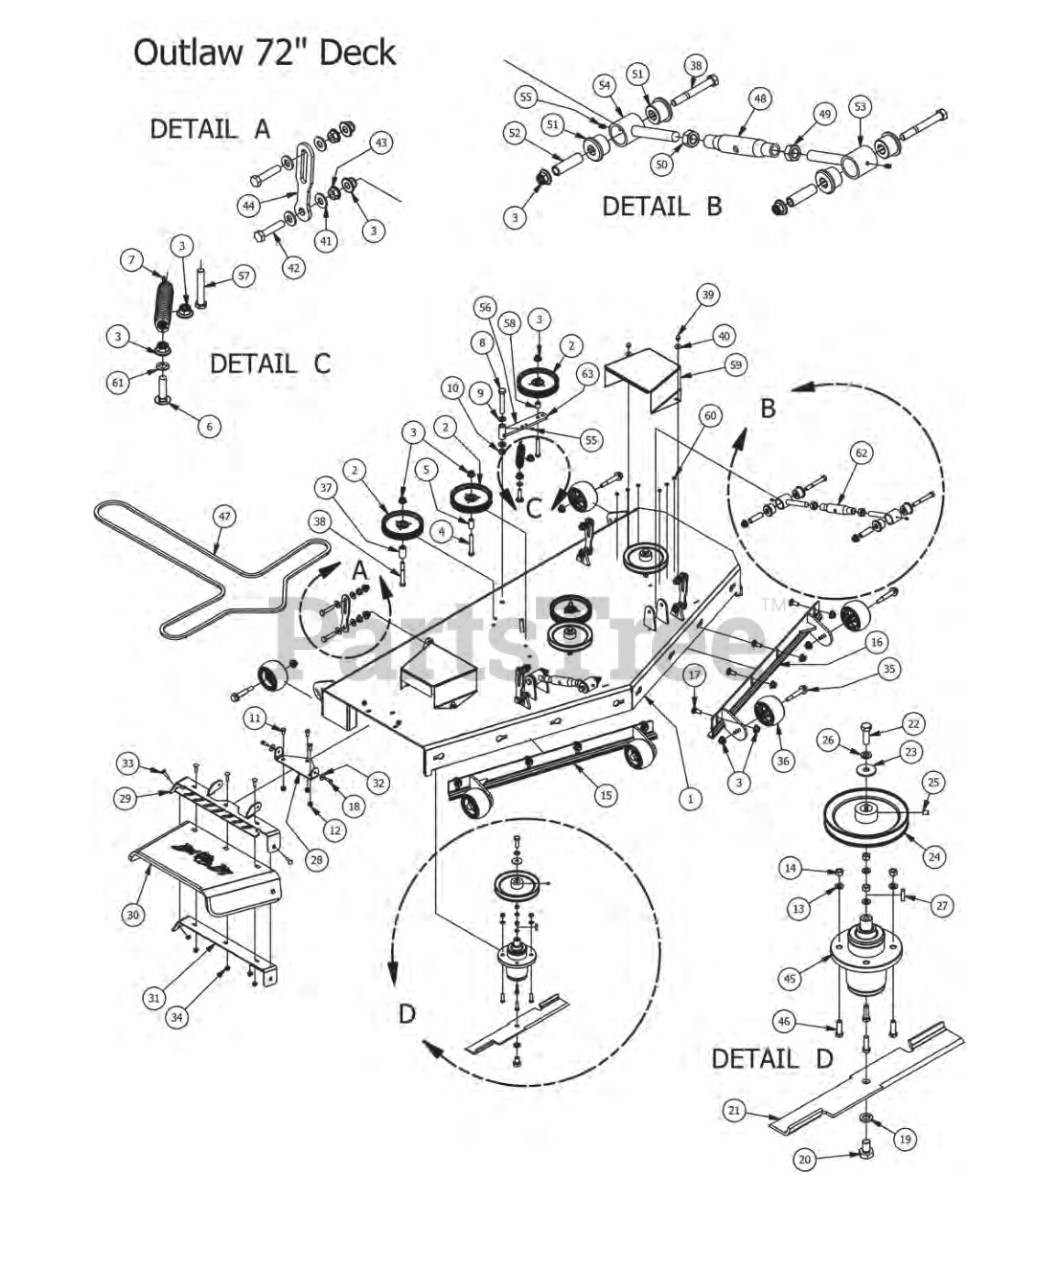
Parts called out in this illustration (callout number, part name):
1	2015 72" Deck
2	5-3/4 Idler Pulley
3	1/2-13 Nylon Flange Nut-Orange
4	1/2 x 3 1/2 Flange Bolt Grade 8
5	502 ID X.75 OD X 1.500 Leng
6	1/2 x 2" Carriage Bolt
7	2015 Deck Idler Spring Outlaws
8	5/8" x 4" Hex Bolt
9	635 ID Plastic Washer
10	5/B-11 Nylon Insert Jam Half Nut
11	3/8" x 3/4" Hex Bolt
12	3/8" Flange Nut
13	3/B Lockwasher Zinc
14	3/B-16 Hex Nuts Zinc
15	72" Deck Adustable Front (Right)
16	72" Deck Adjustable Front (Left)
17	1/2" x 1 1/4 Carriage Bolt
18	5/16" x 1" Bolt
19	5/8" Lock Washer
20	5/8" x 1 1/2" Gr8 Hex Bolt (Fine)
21	72" High Lift Fusion Blade
22	1/2"-20 x 1 1/2-Grade 5 Fine Thread Bolt
23	1/2 Belleville Washer
24	7 Deck Pulley
25	5/16 Set Screw
26	1/2" Lock Washer
27	1/4" x 1" Key
28	Discharge Chute Hanger (deck mounted)
29	60" Discharge Chute Upper Hanger
30	Rubber Discharge Chute
31	60" Discharge Lower Bracket
32	360 ID Plastic Washer
33	5/16" x 1 1/4" Carriage Bolt
34	5/16" Flange Nut Zinc W/Serrations
35	Deck Wheel Bolt
36	Anti-Scalp Rollers.
37	13/4" Pulley Spacer
38	1/2" x 4" Bolt (Grade 8)
39	Acom nut-pulley Cover
40	360 ID Plastic Washer-Black
41	505 Nylon Spacer
42	1/2-13X 2-1/4 GR Hex Bolts
43	1/2" Flange Nut
44	Deck Hanging Tab
45	OUTLAW SPINDLE ASSEMBLY
46	3/8" x 1 1/4" Hex Bolt
47	B202 Belt for 72" Outlaw
49	3/4-10 Left-Handed Hex Nuts Zine
50	3/4-10 Hex Nuts Zinc
53	Turn Left-Handed
54	Right-Handed End
55	1/4" Press in Grease Fitting
56	Deck Idler
57	1/2-13 x GR 5 Hex Bolt Zinc
58	3/4 OD x 1/2 ID x 3/4 Length
59	72 Spindle Cover
60	Black, Round Stick-On Rubber Bumpon
61	517 Square Hole Round Washer
62	Turnbuckle Assembly
63	Deck Idler Assembly - Includes parts: 3,9,59,60,61
